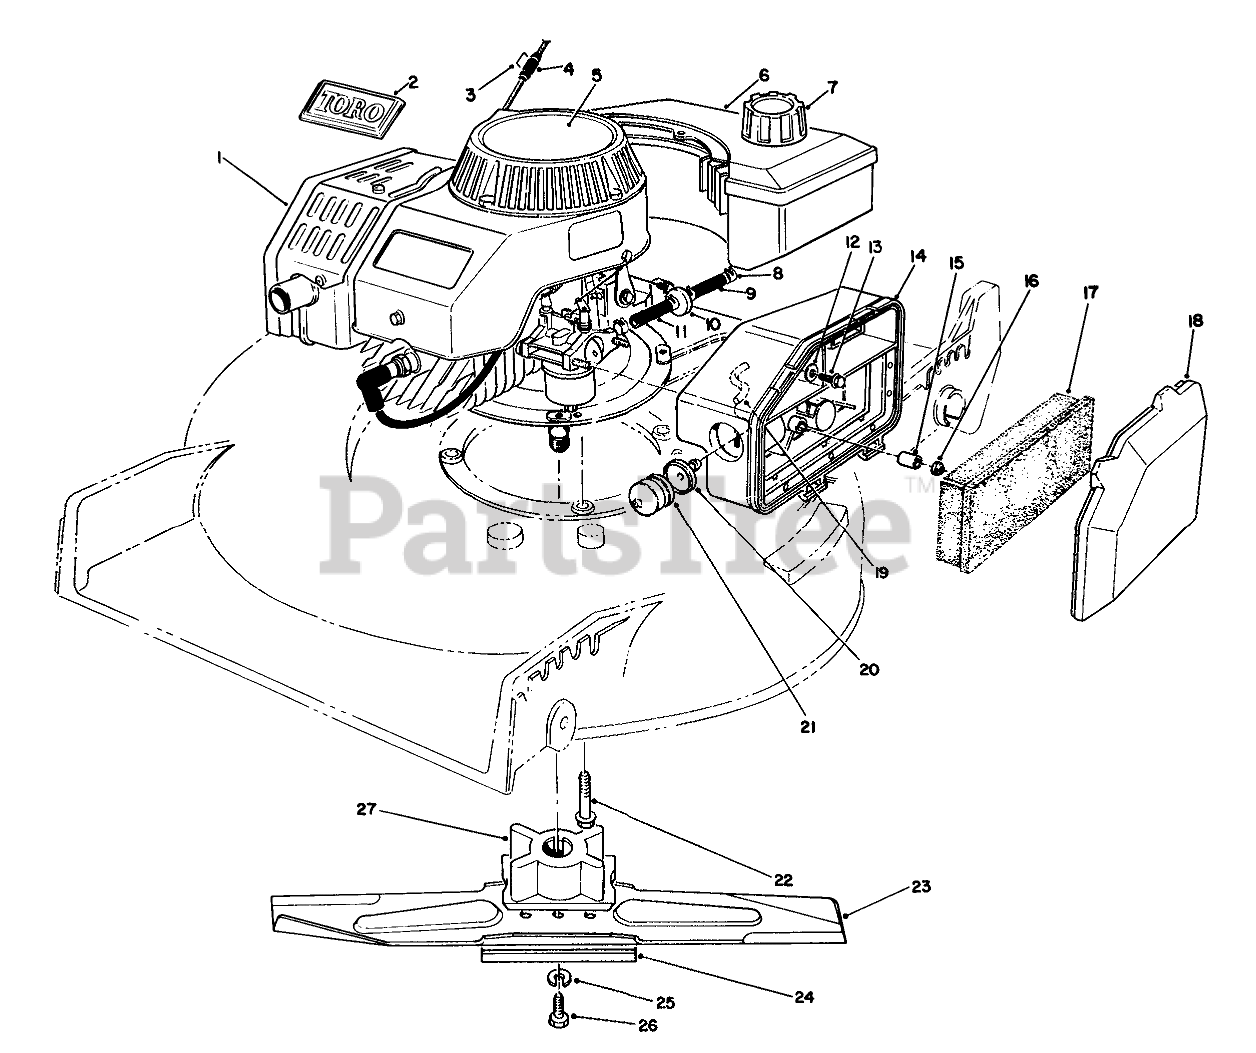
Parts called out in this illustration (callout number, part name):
1	Engine
2	TORO LOGO PLT
3	Staple
5	DECAL - 2 CYC RECOIL
6	Gas Tank Assembly
7	GAS CAP ASM
8	CLAMP-FUEL LINE
9	HOSE-FUEL
10	FILTER-FUEL
11	HOSE-FUEL
12	WASHER-FLAT
13	SCREW-HH
14	BODY-AIR CLEANER
15	SPACER
17	ELEMENT-AIR CLEANER
18	COVER-AIR CLEANER
19	HOSE-PRIMER
20	BODY-PRIMER
21	BULB-PRIMER
22	SCREW-HHF
23	Blade
24	Stiffener
25	WASHER-LOCK
26	SCREW-BLADE
27	BLADE RETAINER
